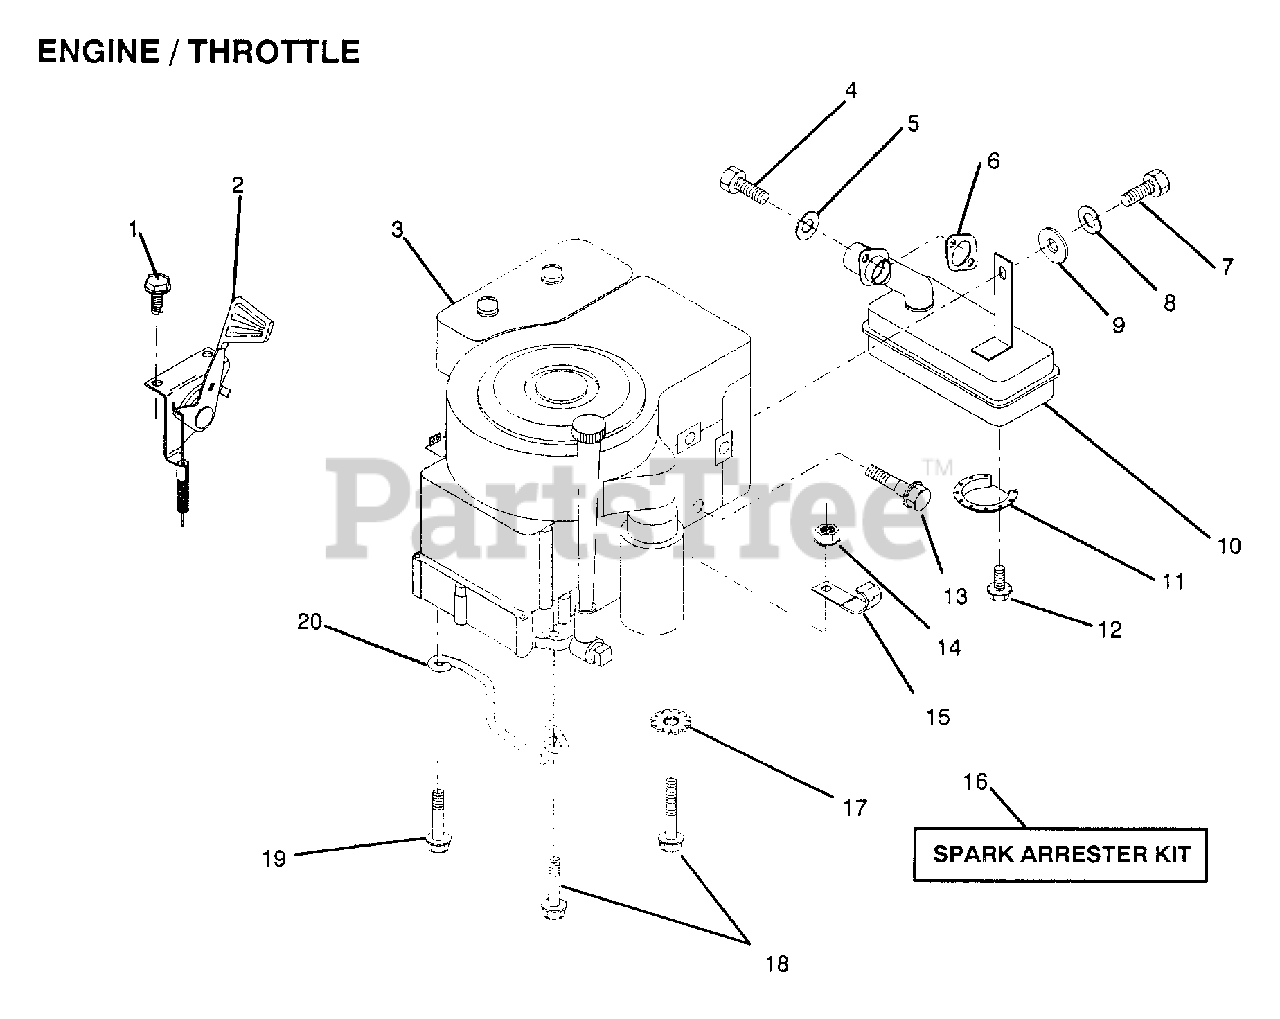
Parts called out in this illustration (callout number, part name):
1	SCREW
4	SCREW
5	LOCKWASHER
8	LOCKWASHER
10	MUFFLER
11	DEFLECTOR.222573
13	BOLT T
14	NUT
15	CLIP T
17	LOCKWASHER
18	SCREW LT
19	SCREW LT
20	"KEEPER,DR BELT GR"
